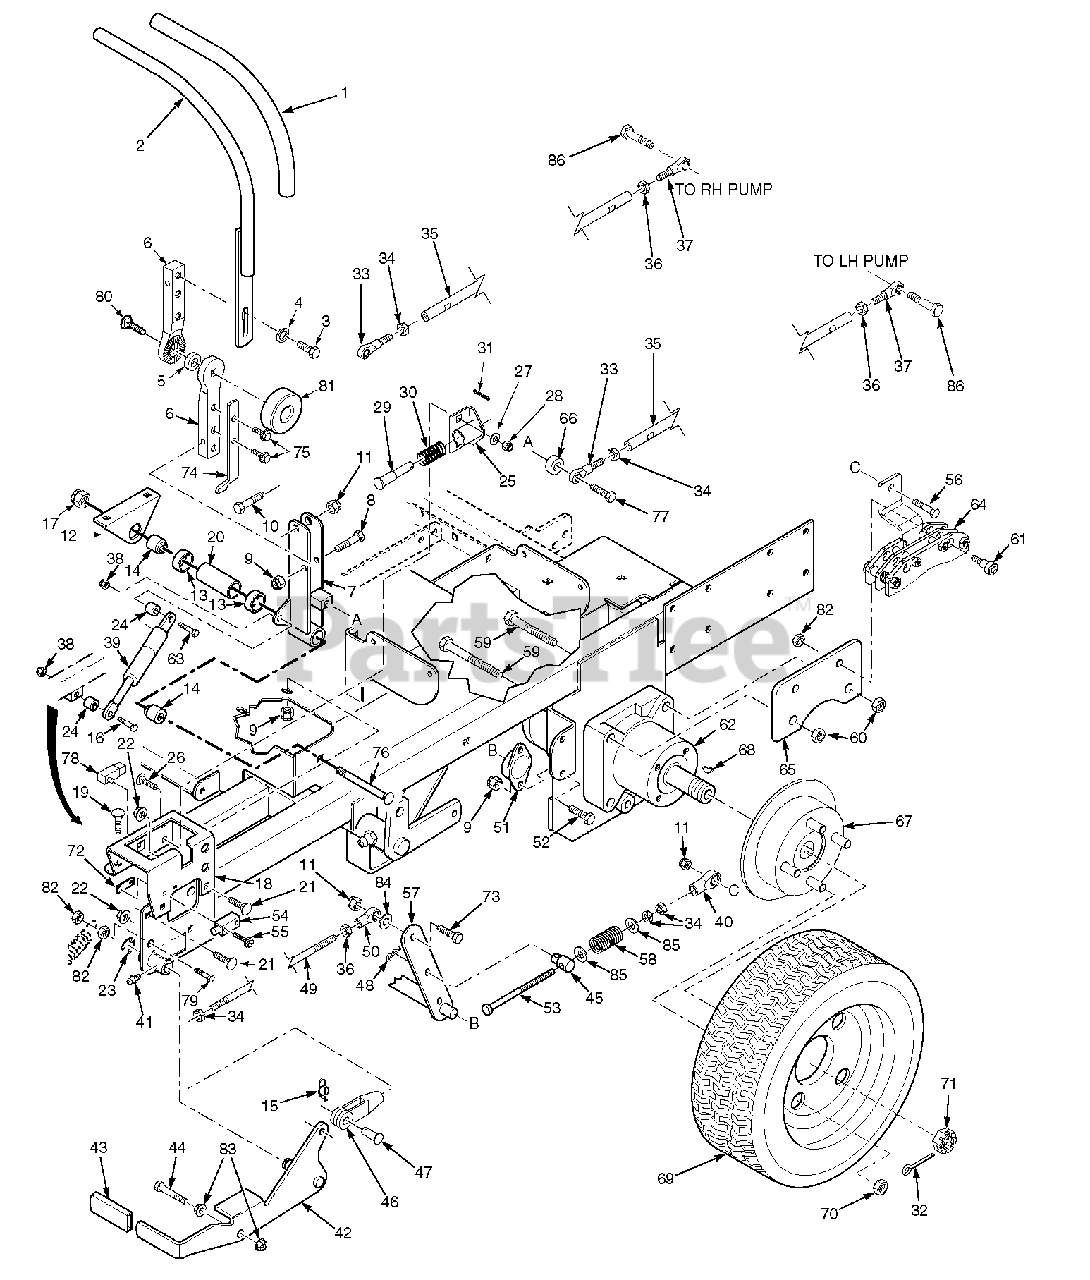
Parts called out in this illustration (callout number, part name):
1	Grip, Handle Bar
2	Handle Bar, LH
2	Handle Bar, RH
3	Bolt, Hex Head 5/16-18 x 1"
4	Lockwasher, 5/16"
5	Rubber Spacer
6	Bar, Control Lever
7	Control Lever Weldment, LH
7	Control Lever Weldment, RH
8	Bolt, Hex Head 5/16-18 x 2"
9	Nut, Hex Elastic Stop 5/16-18
10	Bolt, Hex Head 3/8-16 x 2"
11	Nut, Hex Elastic Stop 3/8-16
12	Mount, Control Linkage
13	Ball Bearings, Neutral Return
14	Spacer
15	Pin, Rue Cotter 3/8 Dia.
16	Bolt, Hex Head, 5/16-18 x 2.75 Zinc
17	Nut, Hex Elastic Stop 5/8-11
18	Bracket, Control Lever LH
18	Bracket, Control Lever RH
19	Bolt, Carriage 5/16-18 x 1"
20	Spacer, Bearing
21	Bolt, Carriage 5/16-18 x 3/4"
22	Nut, Hex Serrated Flange 5/16-18
23	Ring, Retaining 5/8" External "E"
24	Spacer
25	Bracket, Neutral Return
26	Bolt, Carriage 1/4-20 x 3/4"
27	Flatwasher, 1/4" (.312 x .750 x .065)
28	Nut, Hex Elastic Stop 1/4-20
29	Pin, Retaining Spring
30	Spring
31	Roll Pin, Spring 5/32 x 3/4"
32	Pin, Cotter 9/16 x 1-1/2"
33	Rod End, Male 3/8-24 RH Thread
34	Nut, 3/8-24 RH Thread
35	Tube, Control Link
36	Nut, Hex 3/8-24 LH Thread
37	Rod End, Male 3/8-24 LH Thread
38	Locknut, 5/16-18, Elastic Stop
39	Gas Damper
40	Rod End, 3/8-24 RH Female
41	Grease Fitting
42	Lever, Parking Brake
43	Grip, Parking Brake
44	Bolt, Hex Head 3/8-16 x 2-3/4"
45	Swivel Joint
46	Clevis, Traction Control
47	Pin, Clevis
48	Hair Pin Cotter
49	Rod, Parking Brake
50	Rod End, LH Thread
51	Bushing, Self Align
52	Bolt, Hex Head 5/16-18 x 3/4"
53	Bolt, Hex Hd 3/8-24 x 5-1/2"
54	Switch, Parking Brake
55	Screw, Hex Slotted Washer Head #10 32 x 3/4"
56	Bolt, Hex Head 3/8-16 x 1-1/4"
57	Bellcrank, Brake Actuator
58	Spring
59	Bolt, Hex Hd 1/2-13 x 2-3/4" (upper)
59	Bolt, Hex Hd 1/2-13 x 2-1/2" (lower)
60	Locknut, Hex 1/2-13 Center Lock
61	Bolt, Shoulder 1/2 x 3/8-16 x 2-3/4"
62	Wheel Motor, Parker
63	Bolt, Hex Head, 5/16-18 x 1.75, Zinc
64	Brake Caliper
65	Mounting Bracket, Brake
66	Spacer
67	Wheel Hub/Disk Brake Assembly
68	Key, Woodruff 5/16 x 1"
69	Wheel Assembly 24 x 12-12 Turf Master
69	Rim W/Valve Stem
69	Tire, 24 x 12-12 Turf Master
70	Lug Nut, 1/2-20
71	Nut, Hex Castle
72	Threaded Plate
73	Bolt, Hex Head 3/8-16 x 1-1/2"
74	Actuator, Switch
75	Bolt, Hex Serrtd Flng 5/16-18 x 3/4"
76	Bolt, Hex Head 5/8-11 x 4-1/2"
77	Bolt, Hex Head 3/8-16 x 1-1/4"
78	Switch, Handle Neutral
79	Bolt, Hex Head 3/8-16 x 1-1/4" Grd 8
80	Bolt, Carriage 3/8-16 x 1-1/2"
82	Nut, Center Lock 3/8-16
83	Nut, Serrated Flange 3/8-16
84	Flatwasher, 3/8-.391 x .938 x .105
85	Flatwasher, 3/8-.406 x .812 x .065
86	Bolt, Hex Head, 3/8-16 x 1-3/4"
